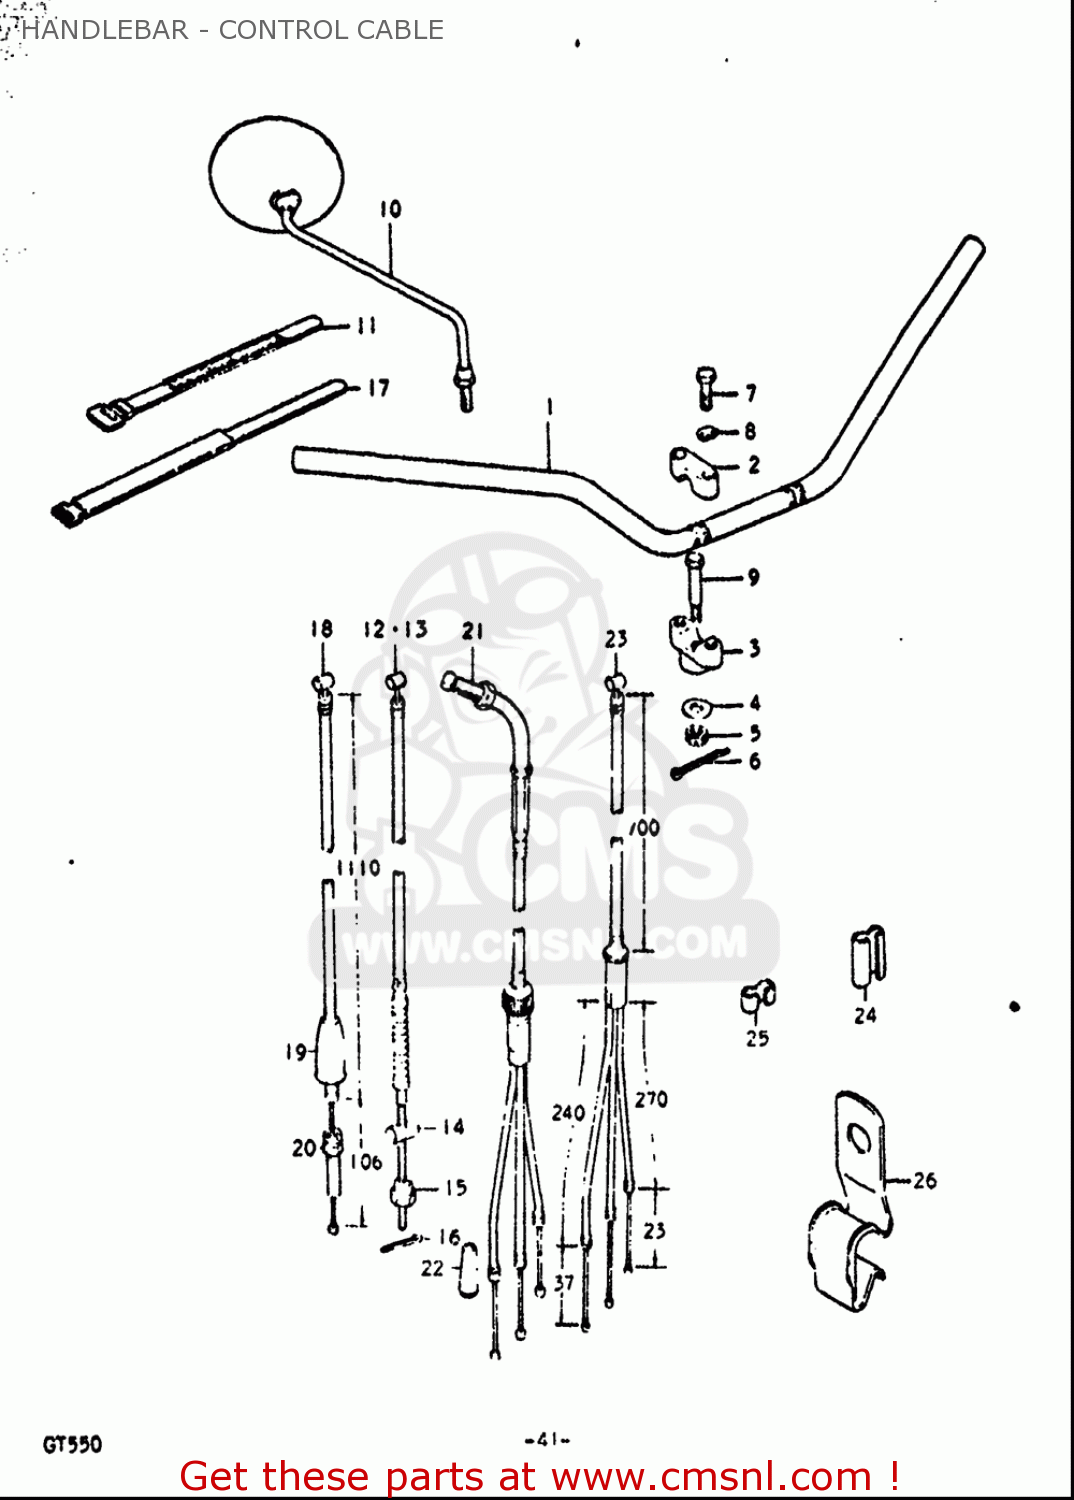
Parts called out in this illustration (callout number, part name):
1	HANDLEBAR
2	HOLDER,HANDLE UPR
3	HOLDER,HANDLEBAR LWR
4	WASHER(10.5X28X2.3)
5	NUT
6	PIN, COTTER
7	BOLT
8	WASHER,LOCK
10	MIRROR ASSY,RE
11	CLAMP(L:120)
12	CABLE,FR BRAKE,R
14	PIN(13X18)
15	NUT
16	PIN
17	CLAMP(L:250)
18	WIRE,CLUTCH
20	NUT
21	CABLE ASSY,THROTTLE
22	SEAL,DUST(7X18X30)
24	CLIP
25	CLIP
26	GUIDE,CABLE
